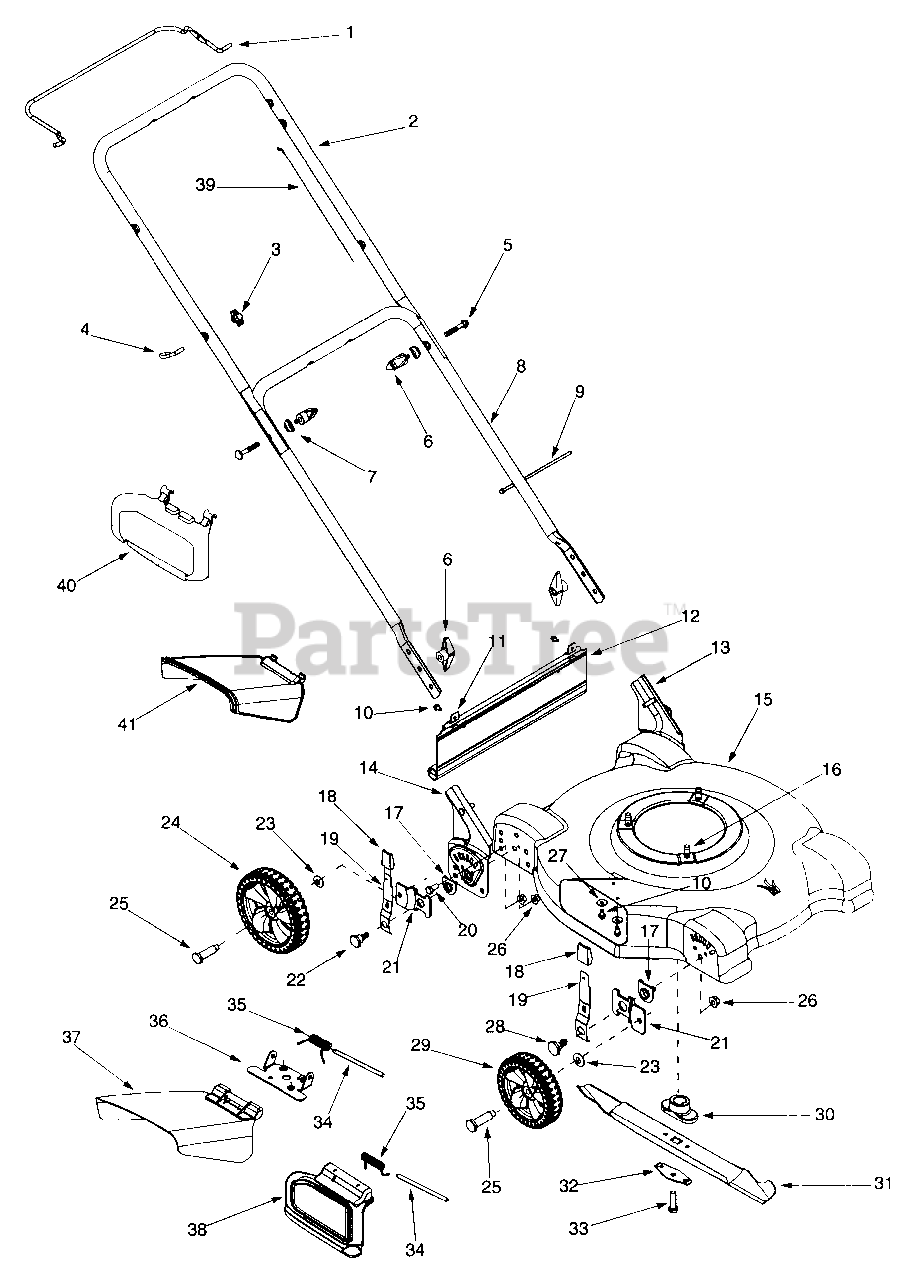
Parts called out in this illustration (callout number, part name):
1	Blade Control Handle
3	Wing Nut
4	Eye Bolt
5	Carriage Bolt 5/16-18 x 2.0
6	Wing Nut
7	Shoulder Washer .320 ID x .93 OD
9	Cable Tie
10	Hex Screw 1/4-14 x .625
11	Hinge Clip
12	Trail Shield
16	Hex Washer Screw 3/8-16 x 1.0
17	Height Adjuster Bearing
18	Height Adjuster Knob
19	Spring Lever
20	Hex Cap Screw 3/8-16 x .75
21	Pivot Arm
22	Shoulder Screw
23	Bell Washer .401 ID x .870 OD
24	Wheel Comp 8 x 1.8
25	Shoulder Screw
26	Flange Lock Nut 3/8-16
27	Bell Washer .265 ID x .75 OD
28	Shoulder Screw
29	Wheel Comp 7 x 1.8
30	Blade Adapter
31	Blade 22"
32	Blade Bell Support
33	Hex Cap Screw 3/8-24 x 1.5
34	Hinge Pin
35	Torsion Spring - Side Discharge
36	Chute Hinge
37	Side Discharge Chute Assembly
38	Mulching Baffle
39	Control Cable - B&S
40	Snap Mulching Plug
41	Snap Discharge Chute
